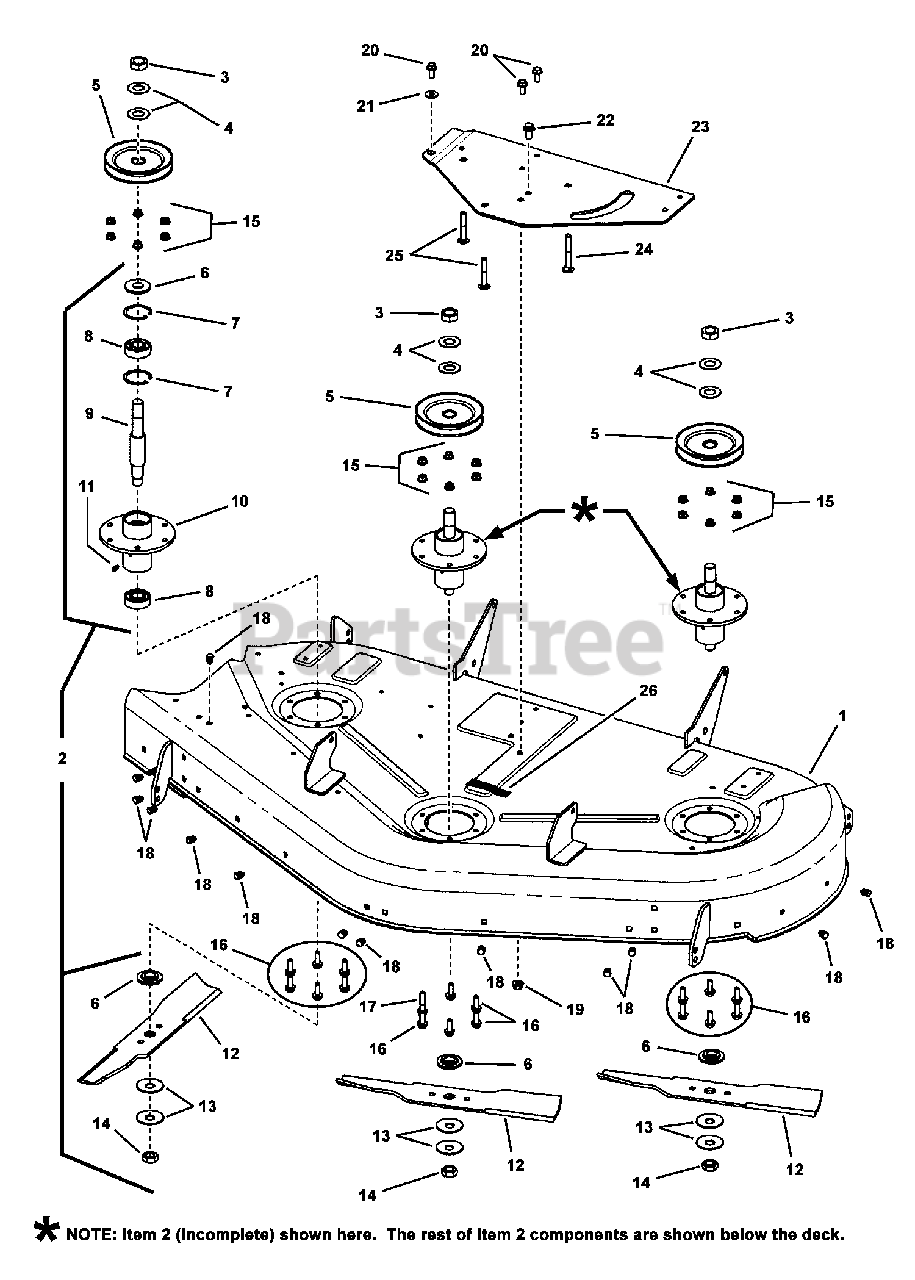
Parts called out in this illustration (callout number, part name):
1	DECK, Weldment 50" Mower
2	GROUP, Spindle, 50" Simplicity
3	NUT, Hex, Jam, 3/4F GR8
4	WASHER, .77X1.5X.06
5	PULLEY, 4.75 O.D.
6	WASHER, Spindle, Powdered Metal
7	RING, Retaining, Extension, 1-3/4
8	BEARING, Spindle
9	SHAFT, Spindle
10	WELD, Spindle
11	LUBE FITTING
12	BLADE, 18-1/8 50" Deck
13	WASHER, Bellville, .656X1.875X.086
14	NUT, Hex, Jam, 5/8F ZP
15	NUT, Hex Flange Lock, 5/16C GR5 YZ
16	CAPSCREW, Hex Head, Whiz Lock, Flange, 5/16C X7/8 YZ
17	CAPSCREW, Hex Head, Whiz Lock, Flange, 5/16C X1-1/2 GR5 YZ
18	PLUG, Hole, Polyethelene
19	NUT, Hex Flange Lock, 3/8C YZ
20	CAPSCREW, Hex Head Flange Taptite, 5/16C X3/4 YZ
21	WASHER, .327X.875X.09 BZ
22	CAPSCREW, Hex Head, Whiz Lock, Flange, 3/8C X3/4 GR5 YZ
23	BRACKET, Idler Pulley, 44/50"
24	CARRIAGE BOLT, 3/8C X2-3/4 GR5 YZ
25	CARRAIGE BOLT, 3/8-16 X 2-1/4, GR5
26	PAD, Rubber Adhesive
